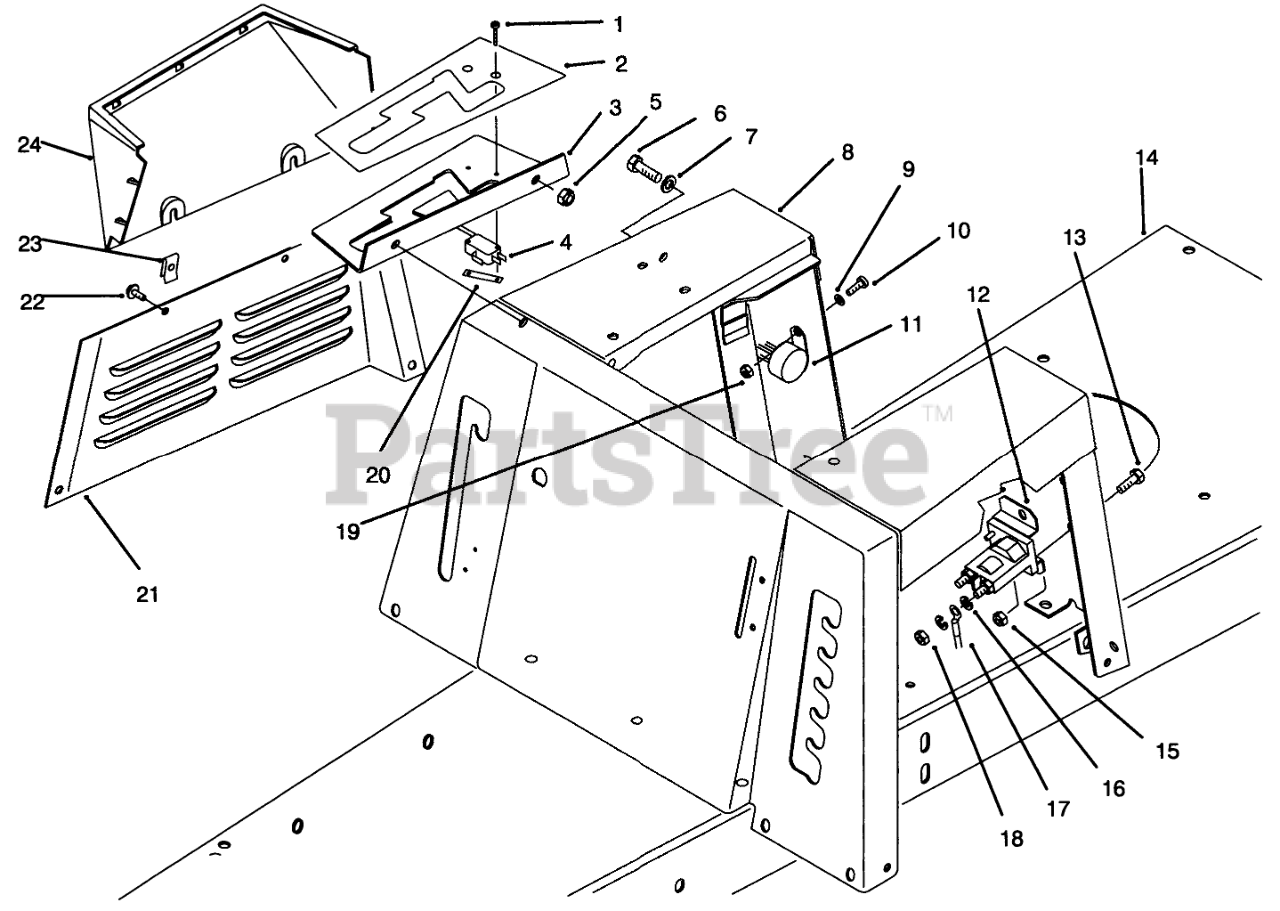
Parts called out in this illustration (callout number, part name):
1	SCREW-HH
2	DECAL - SHIFT PATTERN
3	Gate-Shift
4	SWITCH-MICRO
5	NUT-LOCK, NI
6	SCREW-HH
7	WASHER-PLAIN
8	Body W.A.-Seat Support
9	WASHER-FLAT
11	Module Interlock
12	SOLENOID
13	SCREW-HH
14	Frame
15	NUT-LOCK, NI
16	WASHER-LOCK
17	WIRE ASM
18	NUT-JAM
19	NUT-LOCK, NI
20	NUT-SPEED
21	Panel-Seat Base, R.H.
22	SCREW-HWH
23	NUT-CLIP,U
24	COVER-SHIFT GATE
